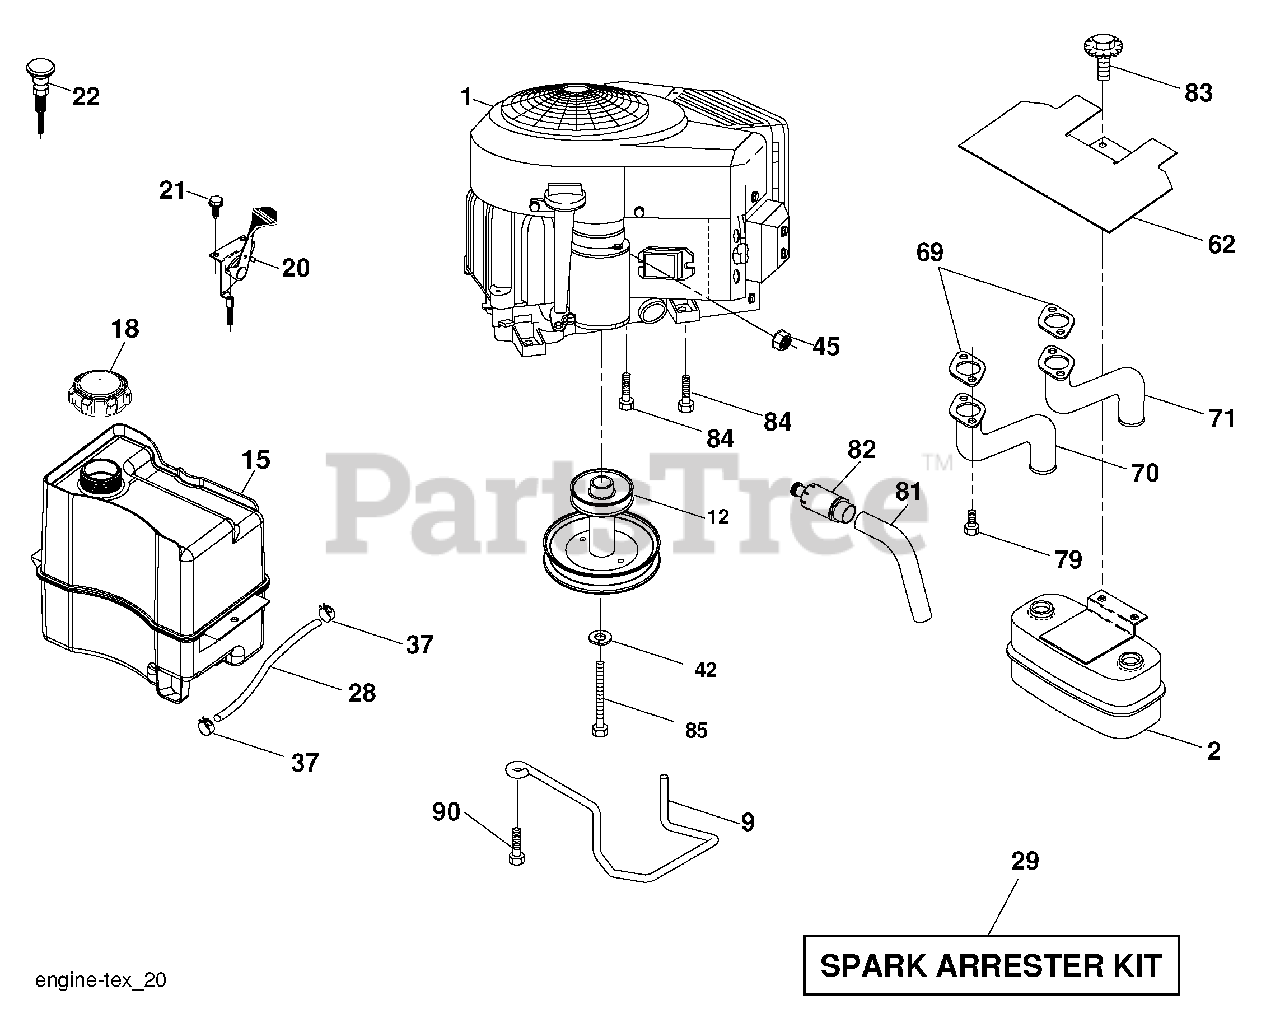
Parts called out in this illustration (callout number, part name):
2	Muffler
9	Keeper Belt Engine
12	Pulley Engine
15	Tank Fuel 3.0
18	Cap Asm
20	Control Throttle
21	Screw 10 x 3/4 Single Lead-
22	Control Choke
28	Fuel Line
29	Spark Arrester Kit
37	Clamp Hose
42	Washer Lock 7/16
45	Nut Keps Hex 1/4-20 unc
62	Shield Heat Muffler
69	Gasket
70	Exhaust Tube RH
71	Exhaust Tube LH
79	Screw Socket Head 5/16-18 x 1
81	Tube Drain Oil Easy
82	Plug Drain Oil
84	Screw 3/8-16 x 1-1/4
85	Bolt Hex 7/16-20 x 4 x 5 Ga.-1.5
87	Bolt 5/16-18 x 3/4
90	Screw 3/8-16 x 1
